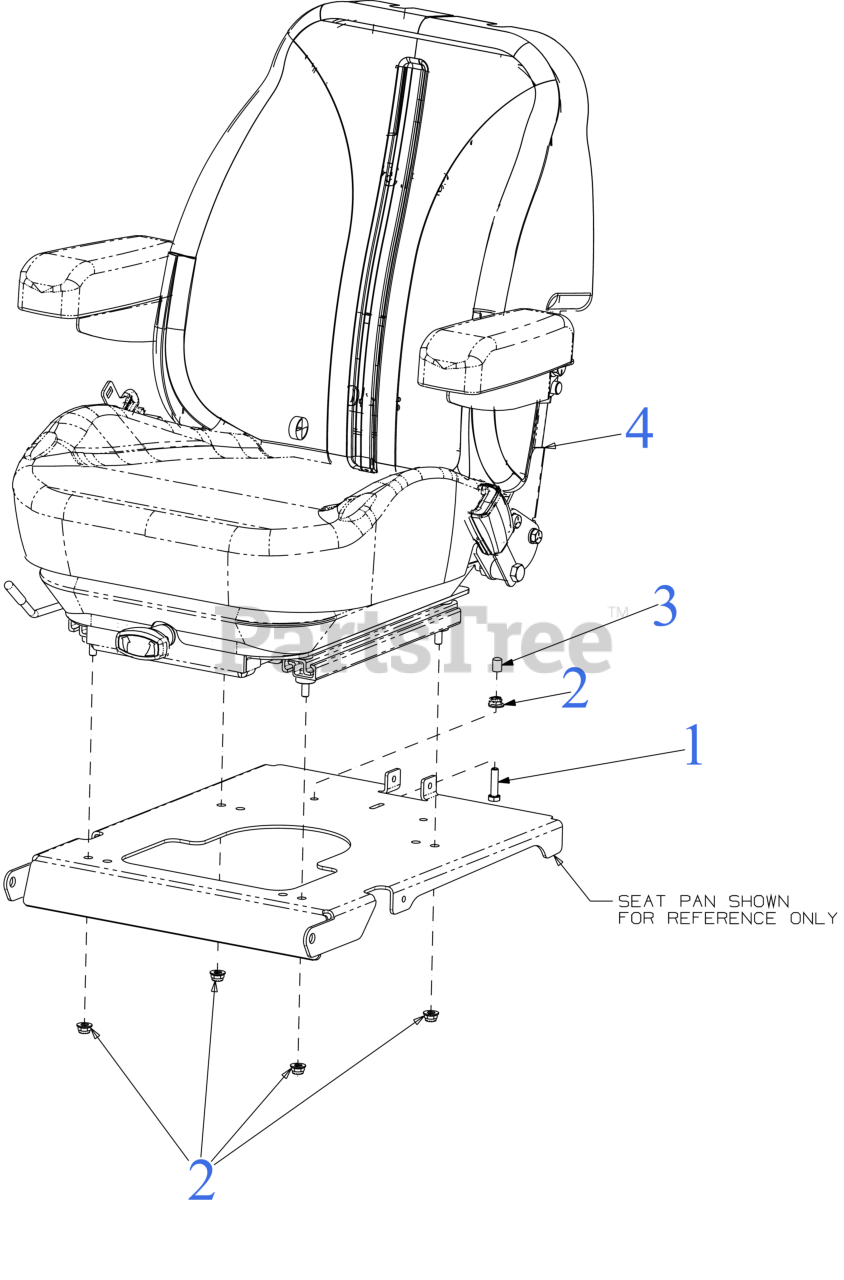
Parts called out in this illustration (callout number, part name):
1	SCREW 5/16-18 x 1.25 GR5
2	FLANGE LOCK NUT 5/16-18
4	SEAT (CUB/SLIDE/SUSP/BELT/ARM)
